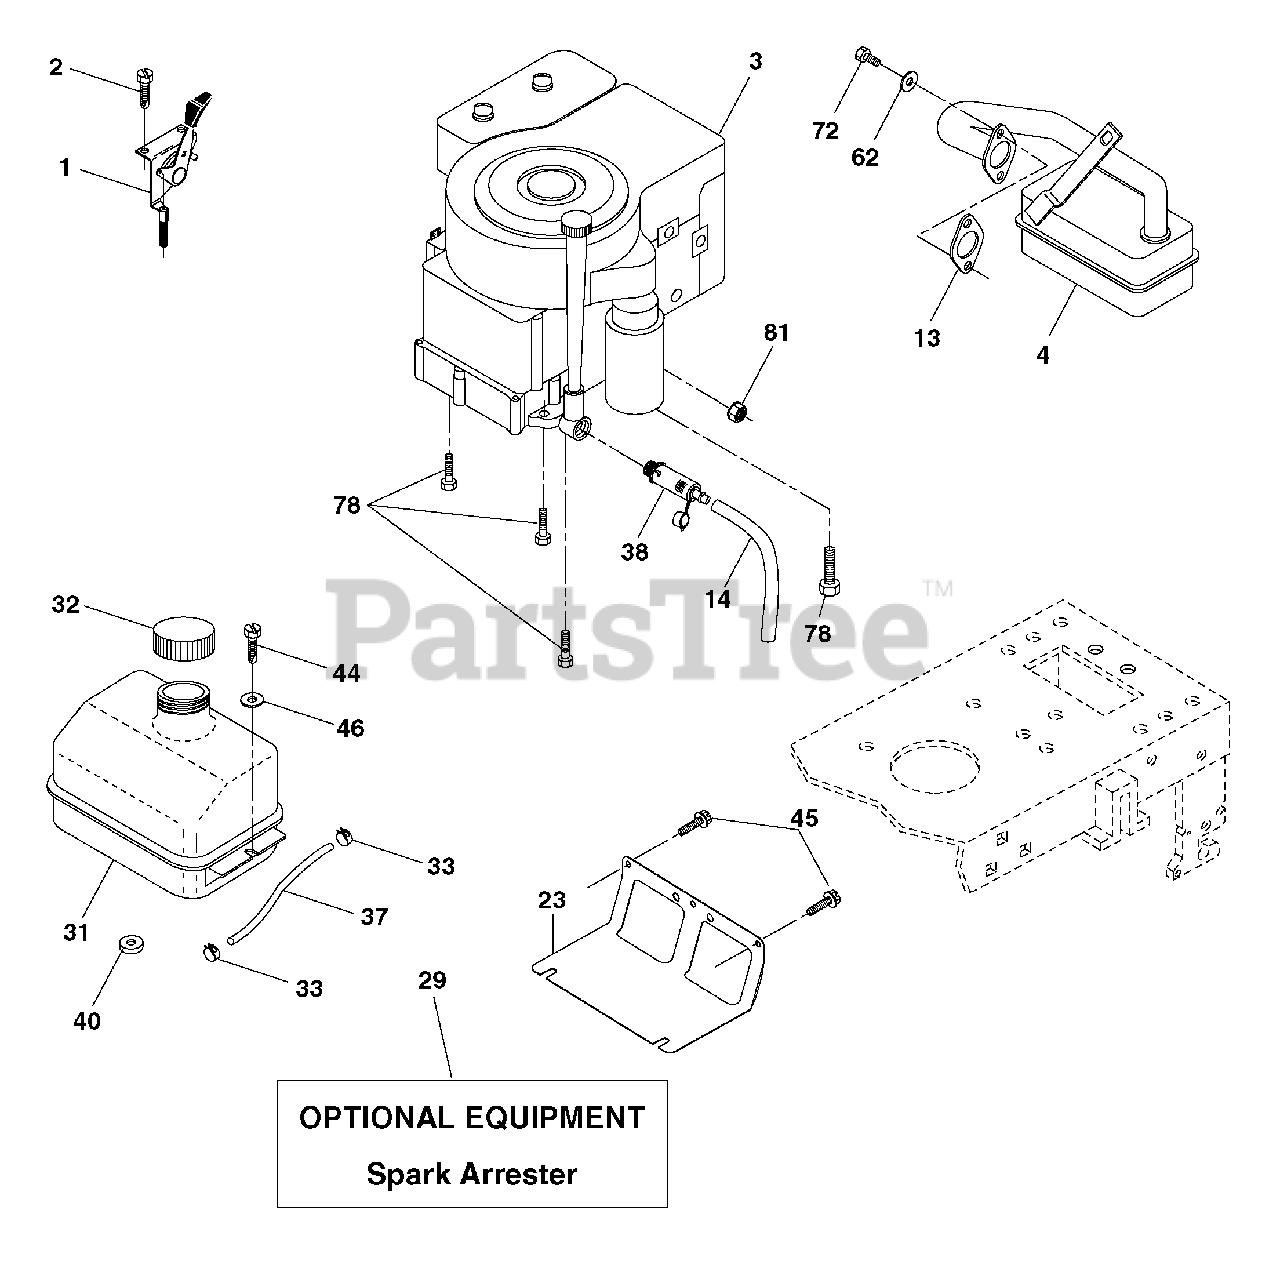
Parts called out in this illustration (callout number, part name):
1	Control, Throttle
2	Screw Hex Thd Cut 1/4-20 x 1/2
4	Muffler
13	Muffler Gasket
14	Tube Oil Drain
23	Shield, Browning/Debris Guard
29	Arrester, Spark
32	Cap, Fuel
33	Clamp, Hose Blk
37	Line, Fuel
38	Plug Drain Oil Easy
40	Bushing Snap
44	Screw Hex Wsh Thdrol 1/4-20 x 3/4
45	Screw Hex Wsh Thdrol 3/8-16 x 3/4
46	Washer 9/32 x 7/8 x 16 Ga.
62	Washer Split
72	Screw Hex Hd Cap 5/16-18 x 3/4
78	Screw 3/8-16 x 1-1/4
81	Nut Keps Hex 1/4-20 unc
